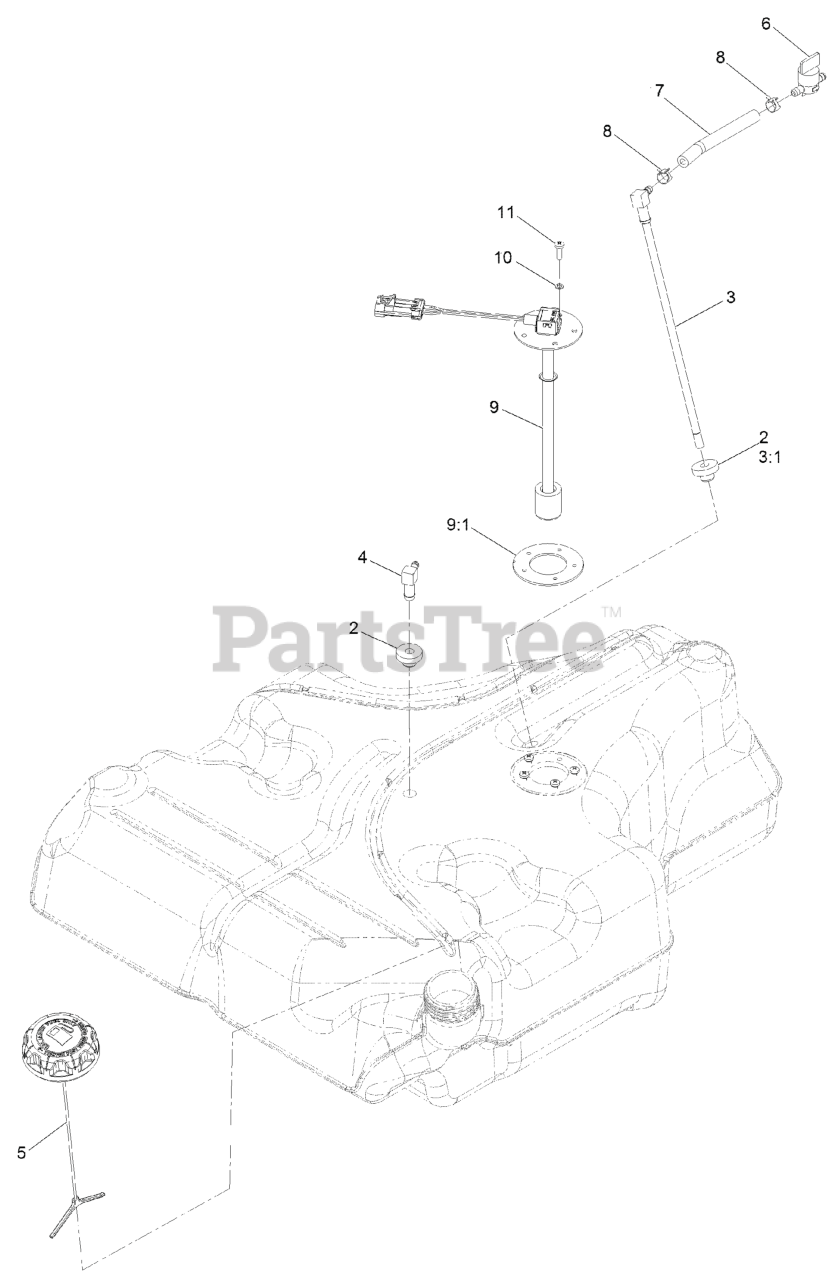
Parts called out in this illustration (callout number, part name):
2	BUSHING
3	FUEL LINE KIT (WITH GROMMET)
3:1	BUSHING
4	FITTING-90 ELBOW
5	CAP-FUEL, RATCHETING
6	VALVE-FUEL
7	HOSE-FUEL
8	CLAMP-HOSE
9	SENDER-LEVEL, FUEL (W/GAS
9:1	Gasket-Sender
10	WASHER-LOCK
11	SCREW-PPH
